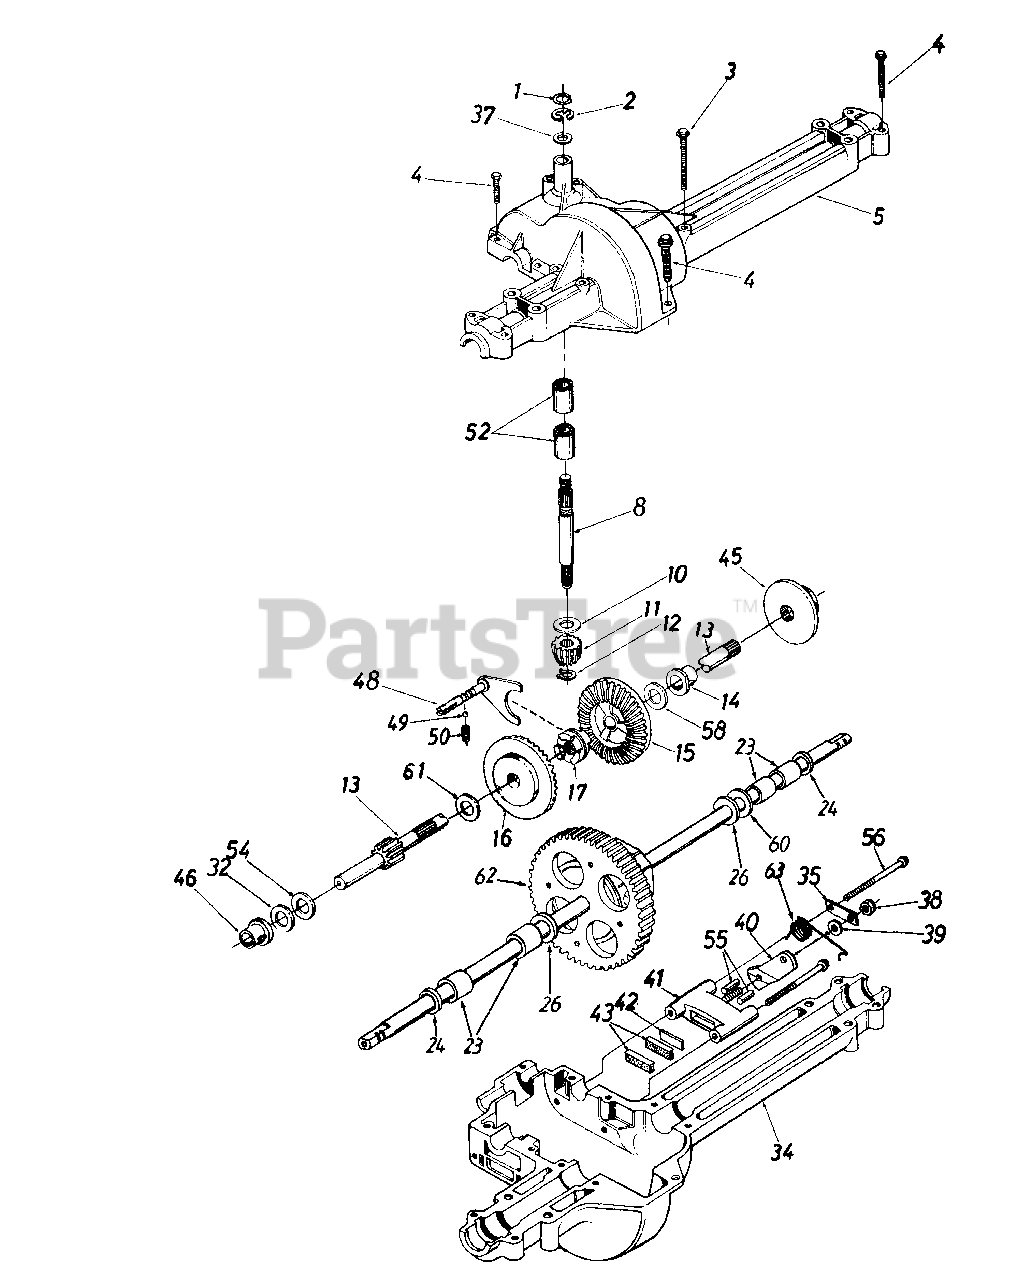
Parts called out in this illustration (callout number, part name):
1	Wire Ring
2	"E"-Ring
3	Hex Wash. TT-Tap Scr. 1/4-20 x 1.75" Lg.
4	Hex Tap Scr. 1/4-20 x 1.25" Lg.
5	Upper Housing
8	Input Shaft
10	Thrust Washer 5/8" I.D. xl.25" O.D.
11	Pinion Input 14T
12	Retaining Ring
13	Drive Shaft--R.H. Brake
14	Flange Brg. 5/8" I.D. x 3/4" Lg.
15	Bevel Gear 42T Small I.D.
16	Bevel Gear 42T Large I.D.
17	Clutch Collar
23	Sleeve Bearing 3/4" I.D. xl.0" Lg.
24	Oil Seal 3/4" I.D.
26	Fl-Wash. .760" I.D. x 1.5" O.D.
32	Washer
34	Lower Housing
35	Anti-Rotation Brkt.
37	Washer
38	Hex Nut 5/16-24 Thd.
39	Fl-Wash. .344" I.D. x .875" O.D.
40	Actuating Arm
41	Brake Yoke
42	Puck Plate
43	Brake Puck
45	Brake Disc
46	Flange Bearing 5/8" I.D. x 15/16" Lg.
48	Shift Fork Ass'y.
49	Ball Detent .250" Dia.
50	Spring Detent
52	Needle Brg. 5/8" I.D. x 1/2"Lg.
54	Fl-Wash. 5/8" I.D. x 1" O.D. x .020 Thk.
55	Actuating Pin 5/16" Dia.
56	Hex Wash Hd. Self-Tap Scr. 1/4-20 Thd.
58	Fl-Wash. 5/8" I.D. x 1" O.D. x .020 Thk.
60	Washer
61	Thrust Washer
62	Differential Ass'y.
63	R.H.--Brake Spring
